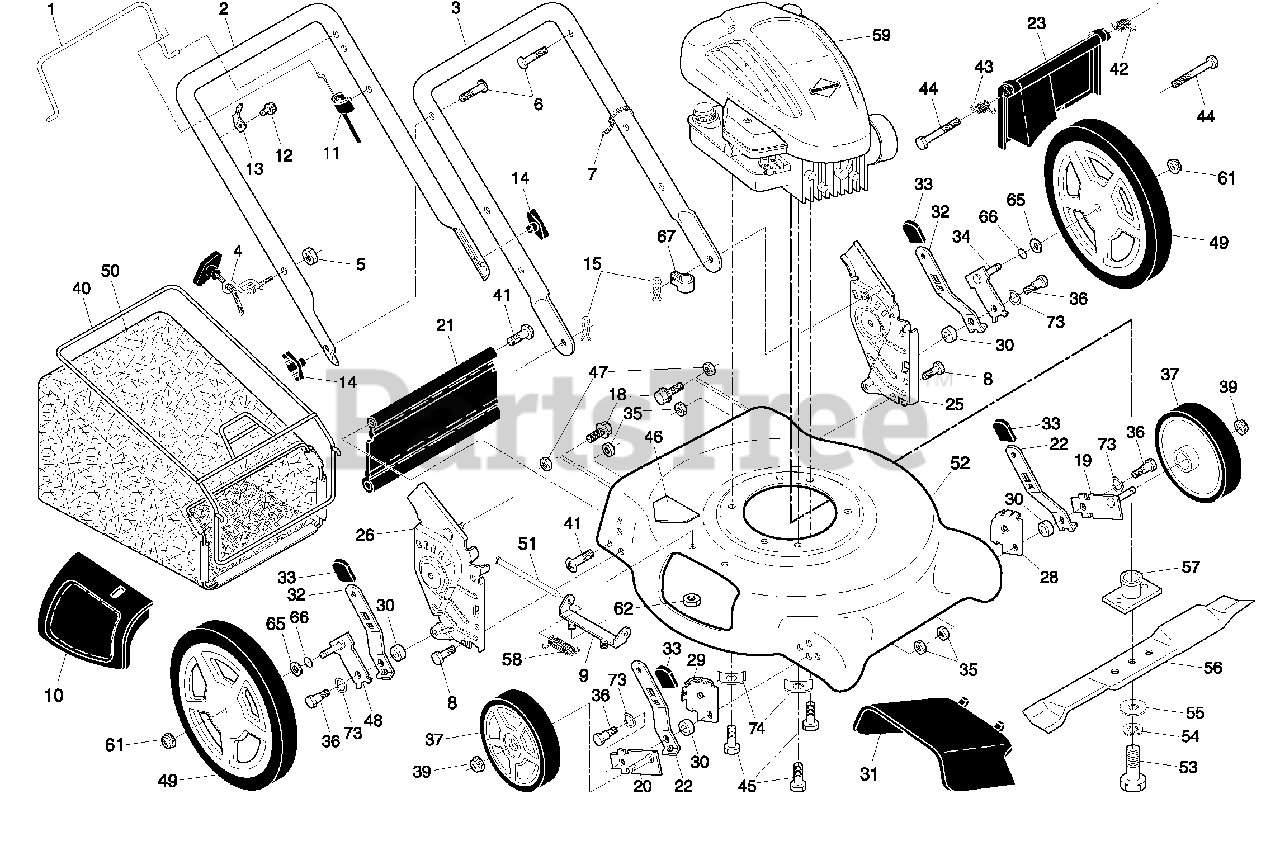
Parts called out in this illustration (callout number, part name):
1	Control Bar
2	Upper Handle
3	Lower Handle
4	Rope Guide
6	Handle Bolt
7	Wire Tie
8	Bolt
9	Hinge Bracket
10	Mulcher Door
11	Engine Zone Control Cable
12	Hex Washer Head Screw
13	Up-Stop Bracket
14	Handle Knob
15	Hairpin Cotter
18	Screw 1/4-20 x 3/8
19	Axle Arm Assembly, Front, LH
20	Axle Arm Assembly, Front, RH
21	Rear Skirt
22	Selector Spring, Front
23	Rear Door Assembly
25	Handle Bracket Assembly, LH
26	Handle Bracket Assembly, RH
28	Wheel Adjusting Bracket, Front, LH
29	Wheel Adjusting Bracket, Front, RH
30	Spacer
31	Discharge Deflector
32	Selector Spring, Rear
33	Selector Knob
34	Axle Arm Assembly, Rear, LH
35	Locknut, Hex 5/16-18
36	Shoulder Bolt 5/16-18
37	Wheel & Tire Assembly, Front, 7"
39	Locknut, Hex, Flanged
40	Frame, Grass Bag
41	Hinge Screw
42	Spring, Rear Door, LH
43	Spring, Rear Door, RH
44	Bolt, Rear Skirt
45	Hex Head Thread Rolling Screw 3/8-16 x 1
46	Danger Decal
47	Nut, Hex
48	Axle Arm Assembly, Rear, RH
49	Wheel & Tire Assembly, Rear, 12"
50	Grass Bag
51	Rod, Hinge
52	Housing Assembly
53	Hex Head Screw 3/8-24 x 1-3/8 Grade 8
54	Helical Lockwasher
55	Hardened Washer
56	21" Blade
57	Blade Adapter
58	Spring, Hinge
61	Locknut, Hex, Flanged
62	Locknut, Hex 1/4-20
65	Washer, Flat
66	O-Ring
67	Clip, Cable
73	Washer, Curved
74	Washer, Special, Engine
74	Operator's Manual, English
74	Operator's Manual, Spanish
74	Repair Parts Manual
